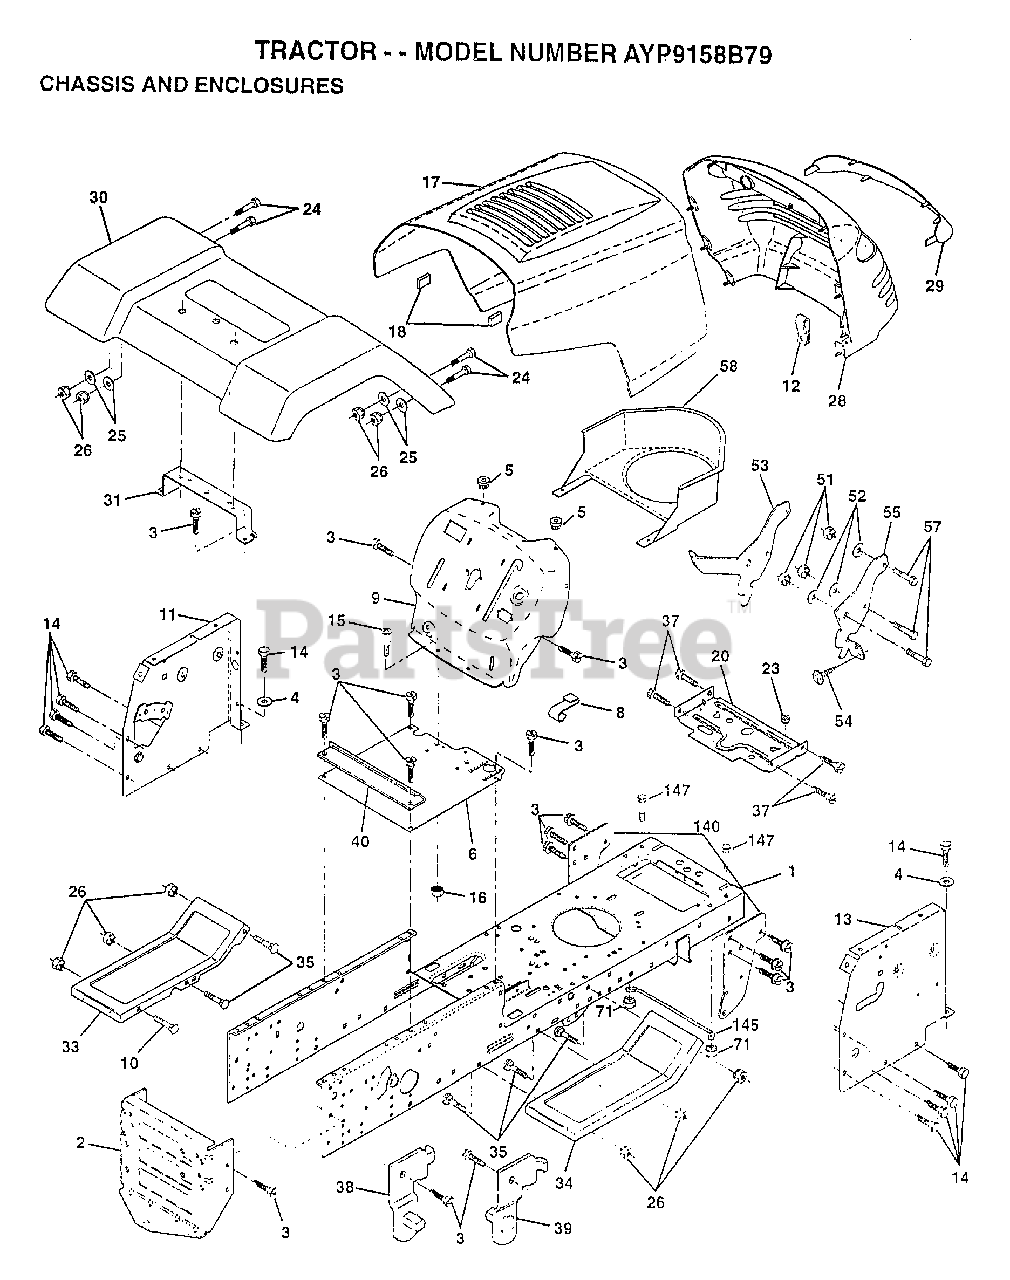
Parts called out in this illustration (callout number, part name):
1	CHASSIS ASM
3	SCREW
4	WASHER
5	BUMPER-HOOD/DASH
6	SADDLE
8	CLIP.RETAINER
9	DASH SILKSCREEN
11	"PANEL-DASH,LH"
12	CLIP.TINNERMAN
13	"PANEL-DASH,RH"
14	SCREW LT
15	SCREW
17	HOOD.STL.PRV.LB
20	"PLATE-MTG,BATT/FU"
24	BOLT
25	WASHER
26	NUT
28	GRILL
29	LENS.EURO.W/DECAL
31	BRACKET SUPT FEND
33	FOOTREST.LT.LT/GT
34	FOOTREST.RH.LT/GT
35	BOLT
37	SCREW LT
38	BRACKET ASM LH
39	BRACKET ASM RH
40	SPACER FENDER LT
51	NUT
53	BRACKET.GRILLE.LH
55	BRACKET.GRILLE.RH
58	AIR DUCT
140	MANUAL.O.8188A79
145	"ROD POVOT,CHASSIS"
147	BOLT LT
